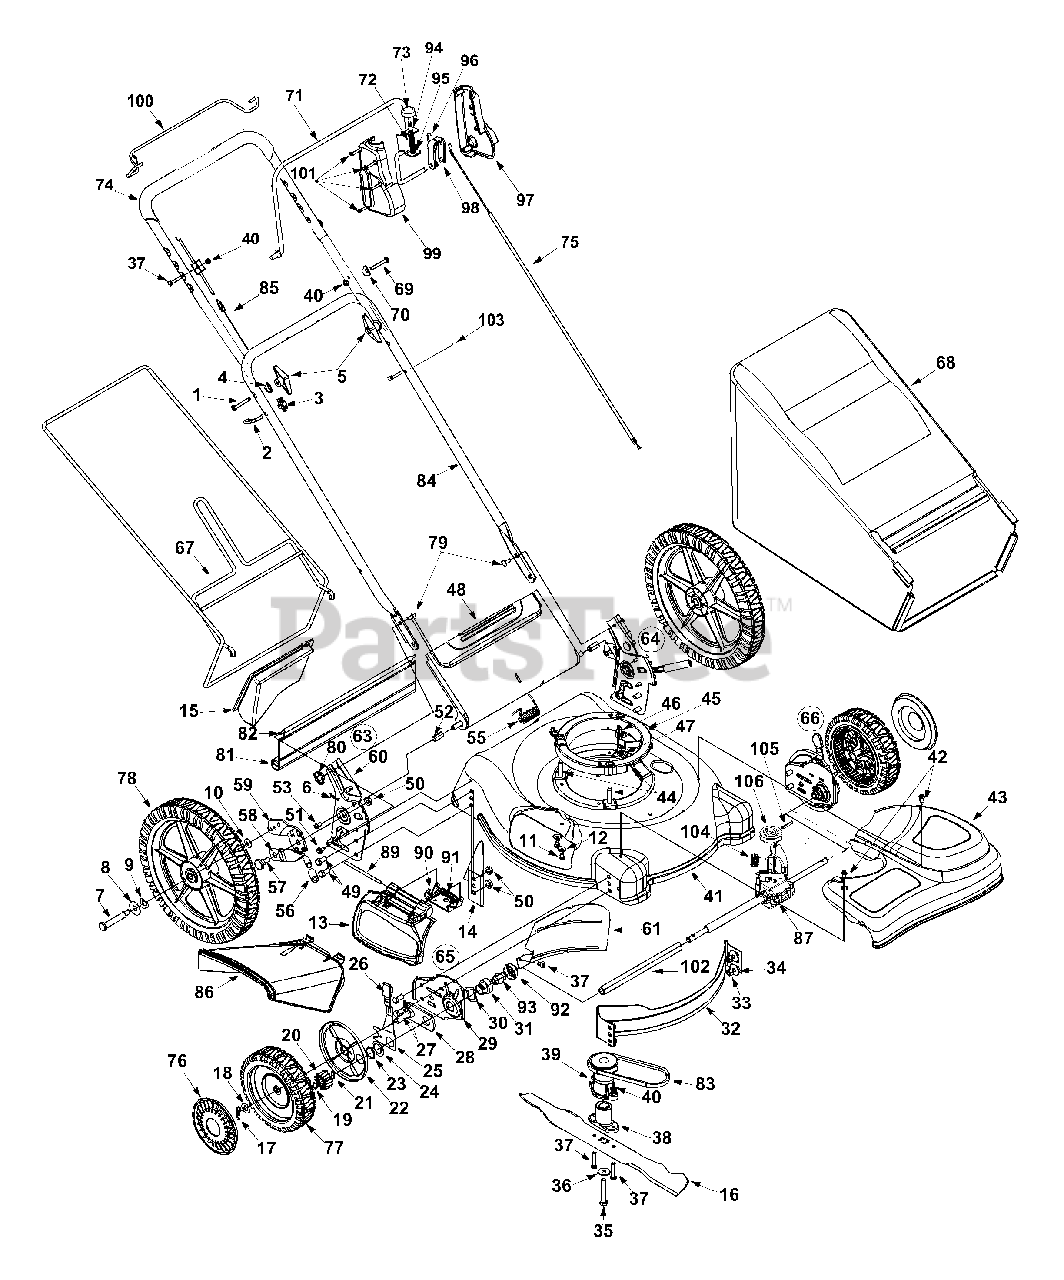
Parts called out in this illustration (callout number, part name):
1	Carriage Bolt
2	Rope Guide
4	Saddle Washer
5	Handle Knob
6	Hairpin Clip
7	Shoulder Screw
8	Flat Washer .510 I.D. x 1.373 O.D.
9	Spring Wash. .500 I.D. x 1.00 O.D.
10	Bell Washer .375 I.D. x .870 O.D.
11	Tapp Screw 1/4-20 x .500
12	Bell Wash. .265 I.D. x .75 O.D.
13	Mulching Plug (Hinged)
15	Mulching Plug
16	Mulching Blade w/Star
16	Standard Blade
17	Hairpin Clip
18	Flat Washer
19	Snap Ring
20	Gear 14T RH
20	Gear 14T LH
21	Dowel Pin
22	Wheel Dust Cap
23	Snap Ring
24	Washer DD 1.5" O.D.
25	Front Lever RH
25	Front Lever LH
26	Knob
27	Hex Screw
28	Pivot Plate Assembly
30	Wave Washer
31	Bearing Support
34	Bell Washer
36	Bell Washer
37	Hex Screw 1/4-20 x 1.5"
38	Blade Adapter
39	Drive Pulley
40	Hex Lock Nut
43	Transmission Cover
45	Engine Spacer Assembly
46	Belt Keeper Pin
47	Hex Nut 1/4-20
50	Flange L-Nut 3/8-16
51	AB Tap Screw 1/4-14 x .625"
53	Pan Hd. Screw 1/4-20 x .5"
54	Pivot Rod
55	Torsion Spring
56	Foam Grip
57	Shoulder Screw
58	Spring Lever
59	Pivot Bar LH
59	Pivot Bar RH
60	Handle Bracket Assembly RH
60	Handle Bracket Assembly LH
62	Scr. AB 1/4-14 x 0.625"
65	Height Adjuster Ass'y Comp. RH
66	Height Adjuster Ass'y Comp. LH
68	Grass Bag w/Half Sail
69	Hex Hd. Cap Screw
70	Saddle Washer
72	Compression Spring
76	Hub Cap
77	Wheel 8 x 2
78	Wheel 14 x 2
79	Carriage Bolt
80	Wing Nut
81	Trail Shield
82	Wire
83	V-Belt
85	Drive Cable
86	Chute Deflector
87	Transmission Assembly Comp.
89	Hinge Pin
91	Torsion Spring
92	Bearing Retainer
93	Bearing Sleeve .50 I.D.
95	Retention Spring
96	Torsion Spring
97	Control Cover LH
99	Control Cover RH
101	Hi-Low Screw
102	Sleeve Spacer LH
102	Sleeve Spacer RH
103	Cable Tie
104	Belt Tension Spring
106	Input Pulley
